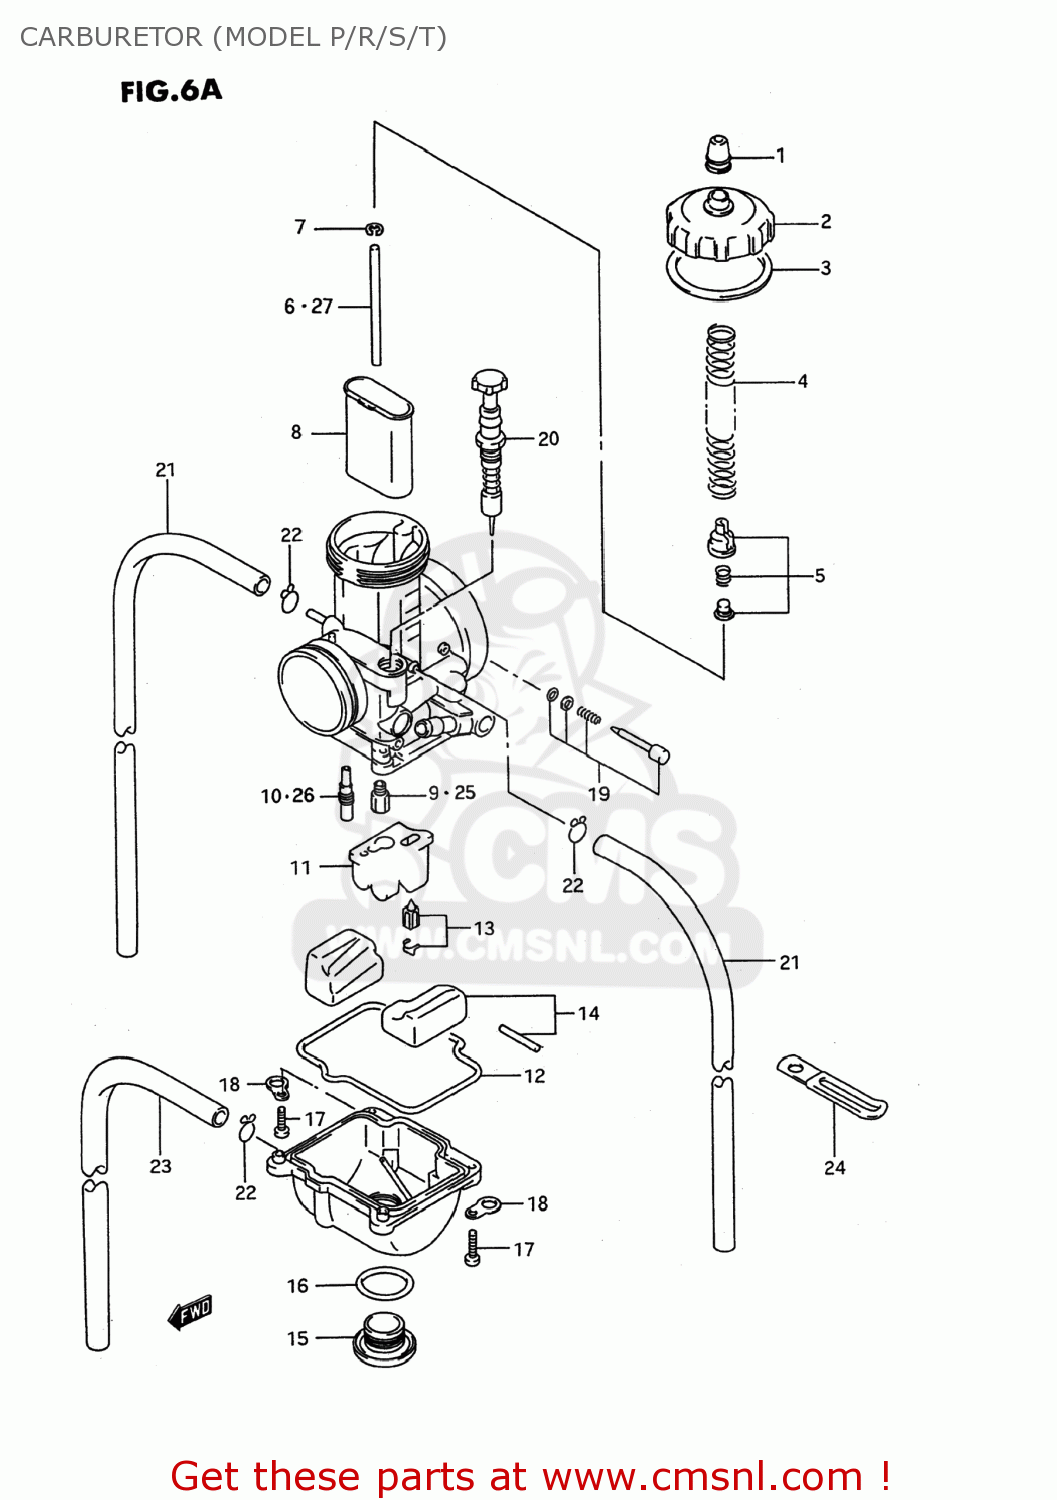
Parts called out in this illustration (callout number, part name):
1	CAP,CARBURETOR
2	CAP,TOP
3	GASKET,TOP CAP
4	SPRING
5	HOLDER SET,CABLE
6	NEEDLE,JET(R1472M 1L)
7	CLIP,NEEDLE
8	VALVE,PISTON(CA:5.0)
9	JET,MAIN(150)
10	JET,SLOW(60)
11	HOLDER
12	GASKET,FLOAT CHAMBER
13	VALVE SET,FLOAT
14	FLOAT SET
15	BOLT,DRAIN
16	O RING
17	SCREW
18	PLATE
19	SCREW SET,AIR
20	PLUNGER ASSY
21	HOSE (4X7X440)
22	CLIP
23	HOSE(3.5X6.5X600)
24	CLAMP
25	JET,MAIN(145)
26	JET,SLOW(50)
27	NEEDLE SET,JET
